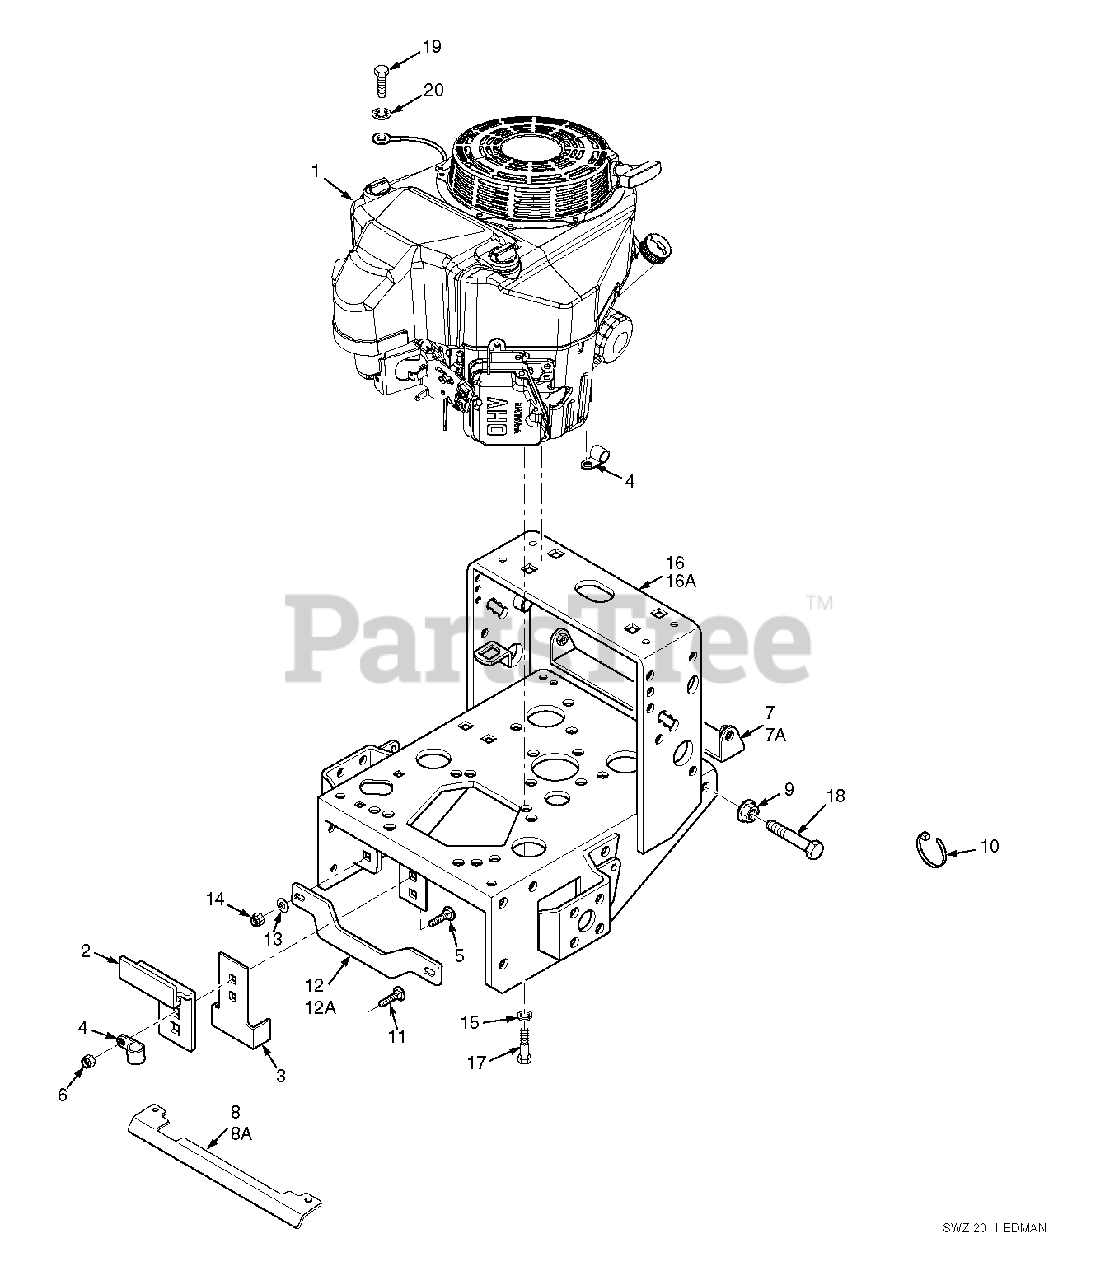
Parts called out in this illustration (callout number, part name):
1	Engine
2	Plate, Clutch Bracket
3	Clutch Bracket
5	Bolt, Carriage 5/16-18 x 1"
6	Nut, 5/16-18 Elastic Stop
7	Pulley Guard, 16" Small Frame
7A	Pulley Guard, 20" Large Frame
8	Heatshield, 16" Small Frame
8A	Heatshield, 20" Large Frame
9	Nut, 5/16-18 Serr. Flange
10	Cable Tie
11	Bolt, Carriage 3/8-16 x 1-1/4"
12	Brace, 16" Small Frame
12A	Brace, 20" Large Frame
13	Flatwasher, .391 x .938 x .105
14	Nut, 3/8-16 Elastic Stop
15	Lockwasher, 3/8"
16	Engine Deck, 16" Wide w/Decals
16A	Engine Deck, 20" Wide w/Decals
17	Bolt, Hex Head 3/8-16 x 1-1/4"
18	Bolt, 5/16-18 x 2" Hex Head
19	Bolt, Hex Head M8-1.25 x 16
20	Lockwasher, 5/16" Ext. Tooth
